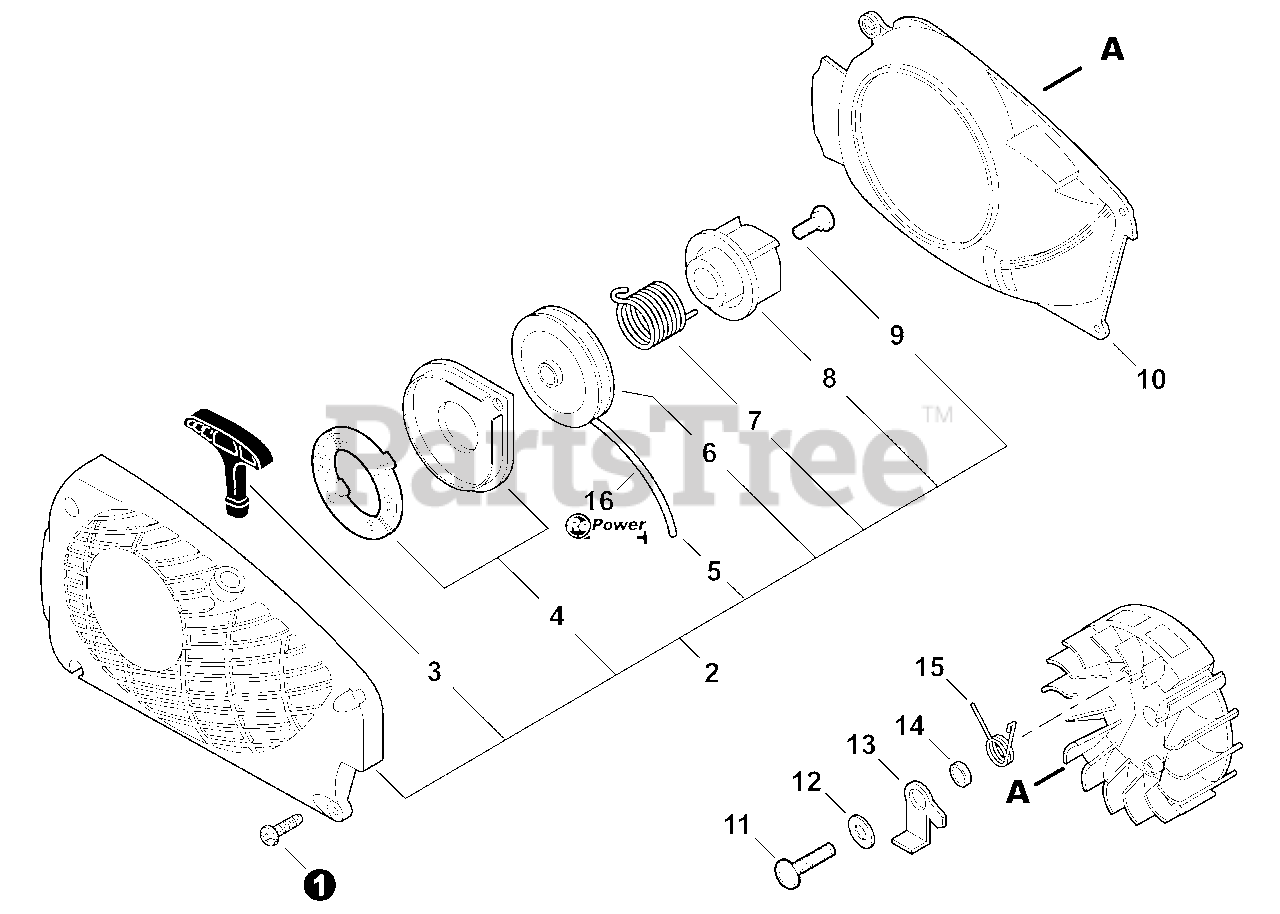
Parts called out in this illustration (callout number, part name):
1	SCREW 4×16
2	STARTER ASSY, RECOIL
3	GRIP, STARTER
4	SPRING KIT, RECOIL
5	ROPE, STARTER 3.5×900
6	REEL, ROPE
7	SPRING, TORSION
8	PAWL CATCHER
9	SCREW
10	COVER, FAN
11	BOLT 5×14
12	WASHER 5.5×12×0.8
14	SPACER 5.2×8×2.1
15	SPRING, TORSION
16	ROPE, STARTER - REPOWER BULK
